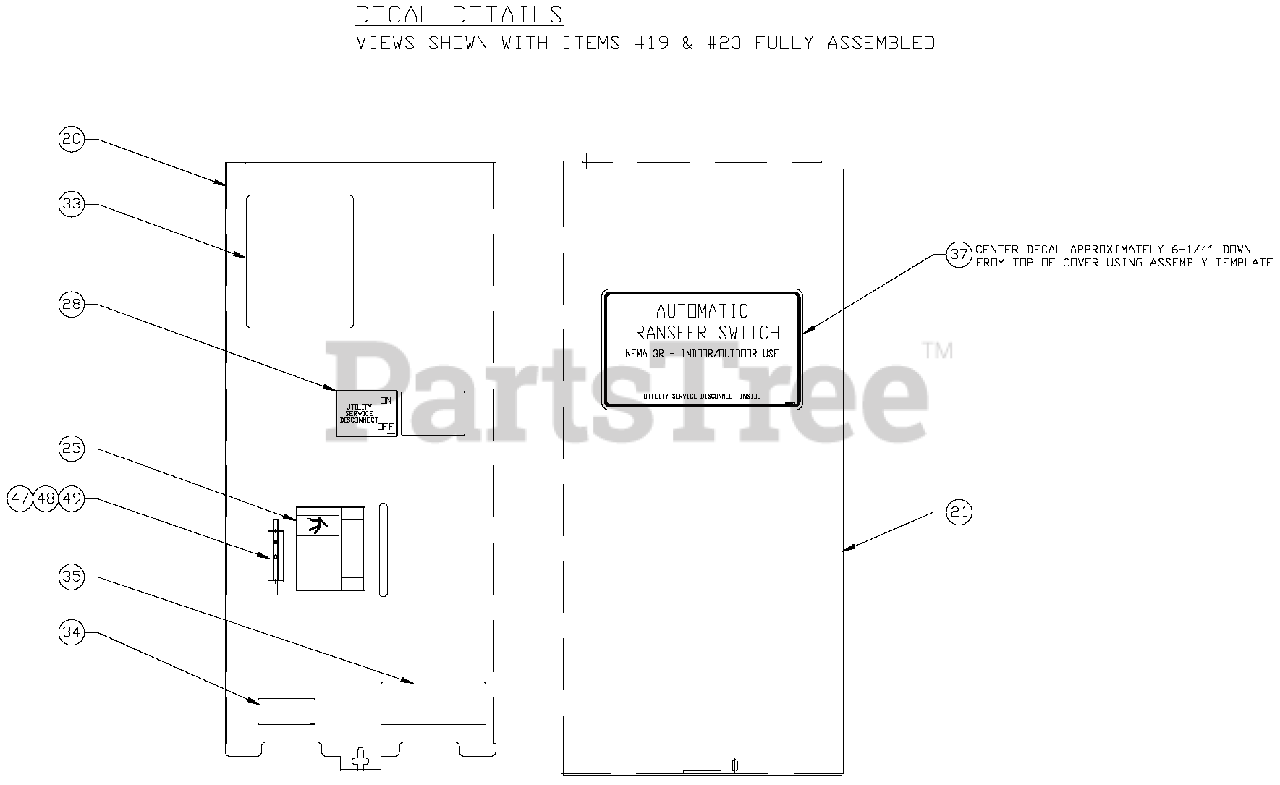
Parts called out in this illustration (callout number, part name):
20	COVER, INSIDE 200A DUAL BREAKER
21	COVER, TRANSFER SWITCH
22	CB RISER BRACKET 200A GENERAC
23	SUBPLATE, 200A SE XFER SW
25	DECAL, MANUAL OPERATING HANDLE
28	DECAL, UTILITY DISCONNECT
33	DECAL, TEST SEQUENCE
34	DECAL LIVE CIRCUIT ENG/FRN/SPN
35	DECAL, TERMINAL SHOCK HZD BI
37	DECAL FRNT CVR ATS 3R SER DIS
47	BRACKET, ARM EXTENDER
48	RIVET POP .156 X .362 AL
49	ARM EXTENDER PIN
